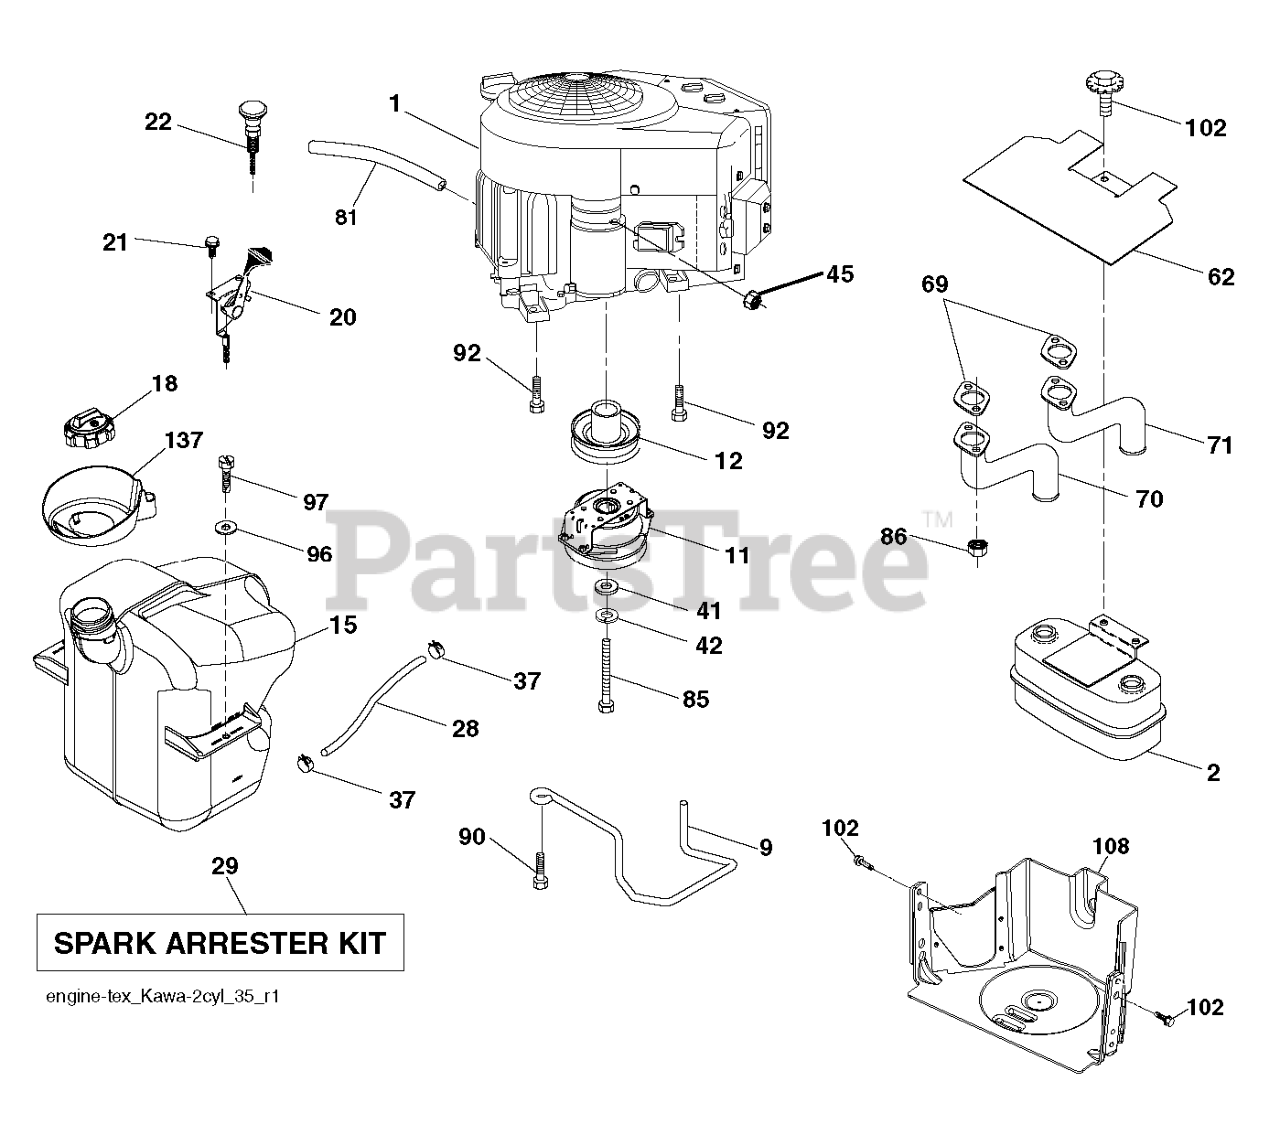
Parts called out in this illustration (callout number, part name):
2	MUFFLER.ASM.TWN.EXTNDED.DFLCTR
9	KEEPER BELT ENGINE
11	CLUTCH.ELECTRIC.LT.48"*
12	PULLEY.ENGINE.TUFFTORQ
15	FUEL TANK TANK. ASSEMBLY. EXTE
18	CAP.ASM.FUEL.2.25"TOP.TURN
20	CONTROL.THROTTLE.COBRA.BLACK
21	SCREW.#10 X 0.750.BOS
22	CONTROL, CHOKE
28	LINE.FUEL.20
29	KIT.SPARK ARRESTOR 794945 B&S
37	HOSE CLAMP
42	LOCKWASHER
45	NUT
62	SHIELD.HEAT.MUFFLER
70	TUBE.EXHAUST.LH.FR961/FR730
71	TUBE.EXHAUST.RH.FR961/FR730
81	TUBE, DRAIN OIL ASM.
85	BOLT HEX 7/16-20X4-1/4"
86	NUT.HEX.FLANGE.TOPLOCK
87	BOLT 5/1618UNC X 3/4 W/ SEMS
90	SCREW 3/8-16X1
92	SCREW 3/8-16X1
96	WASHER
97	SCREW HEXWSHR 1/4-20X3/4
102	SCREW 5/16-18X1
108	COVER PULLEY
